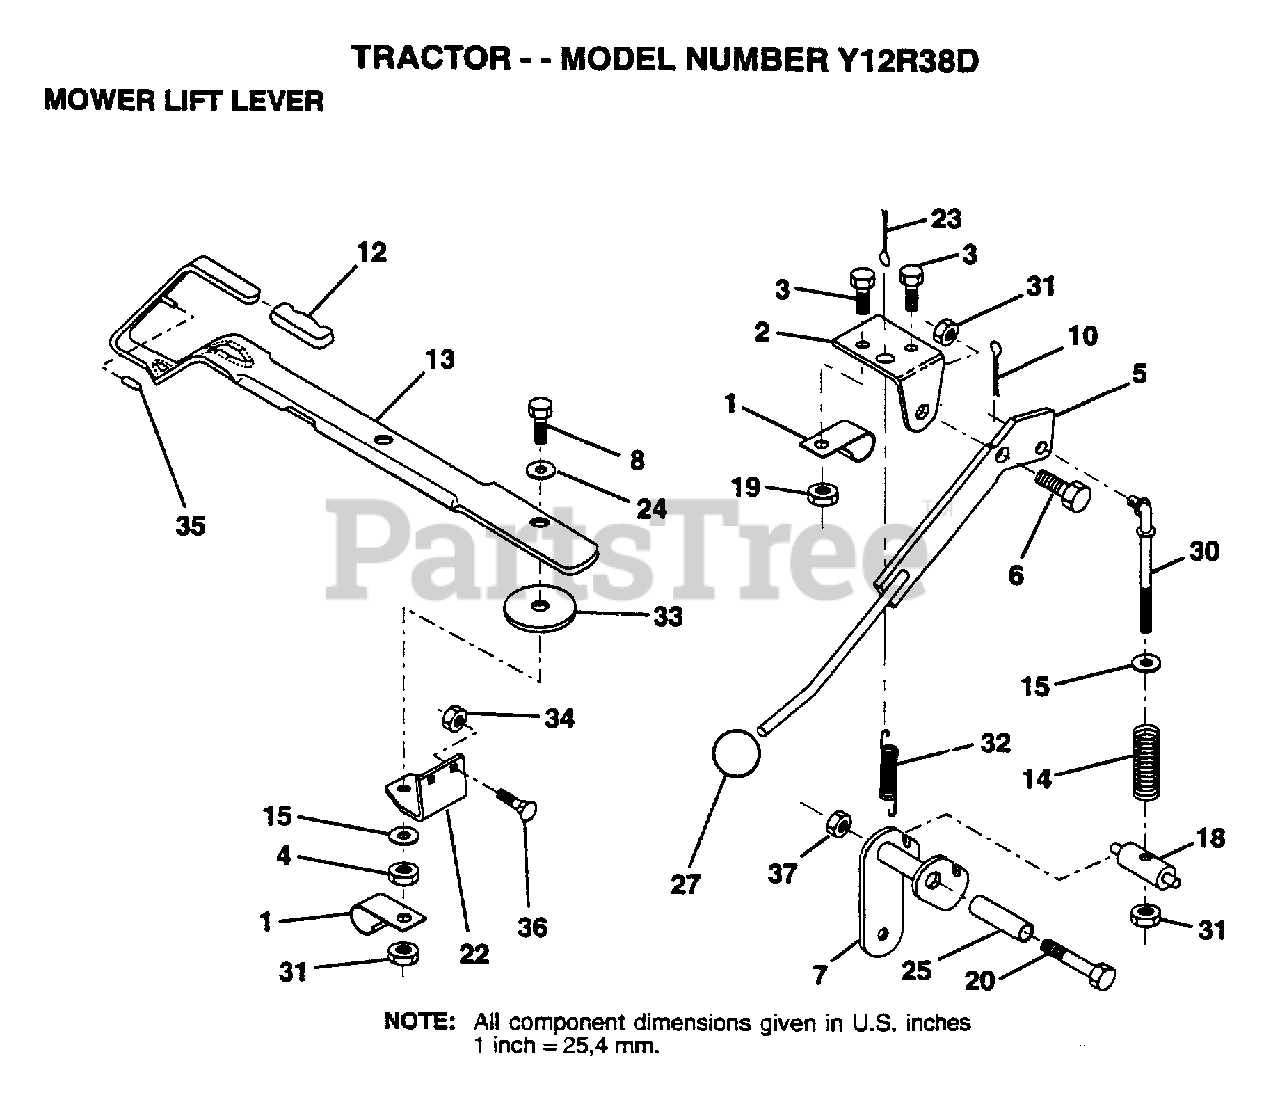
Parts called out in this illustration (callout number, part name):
1	"CLIP,INSULATOR"
2	BRKT CLUTCH
3	BOLT HXHD FIN
4	NUT
5	LEVER.ASM.CLUTCH
6	"BOLT, SHOULDER LT"
7	ARM.CLUTCH.ASM
8	BOLT
10	COTTER PIN
12	GRIP HANDLE
13	LEVER LIFT LR
14	COMP CLUTCH SPRNG
15	WASHER HYT
18	TRUNNION
20	BOLT
22	LIFT LEVER BRKT
24	WASHER
25	TUBE SPACER
27	KNOB
30	ROD TENSION CLUTC
31	NUT
32	SPRING EXT
33	WASHER
34	NUT
35	VINYL CAP RED
36	BOLT
38	LOCKNUT
